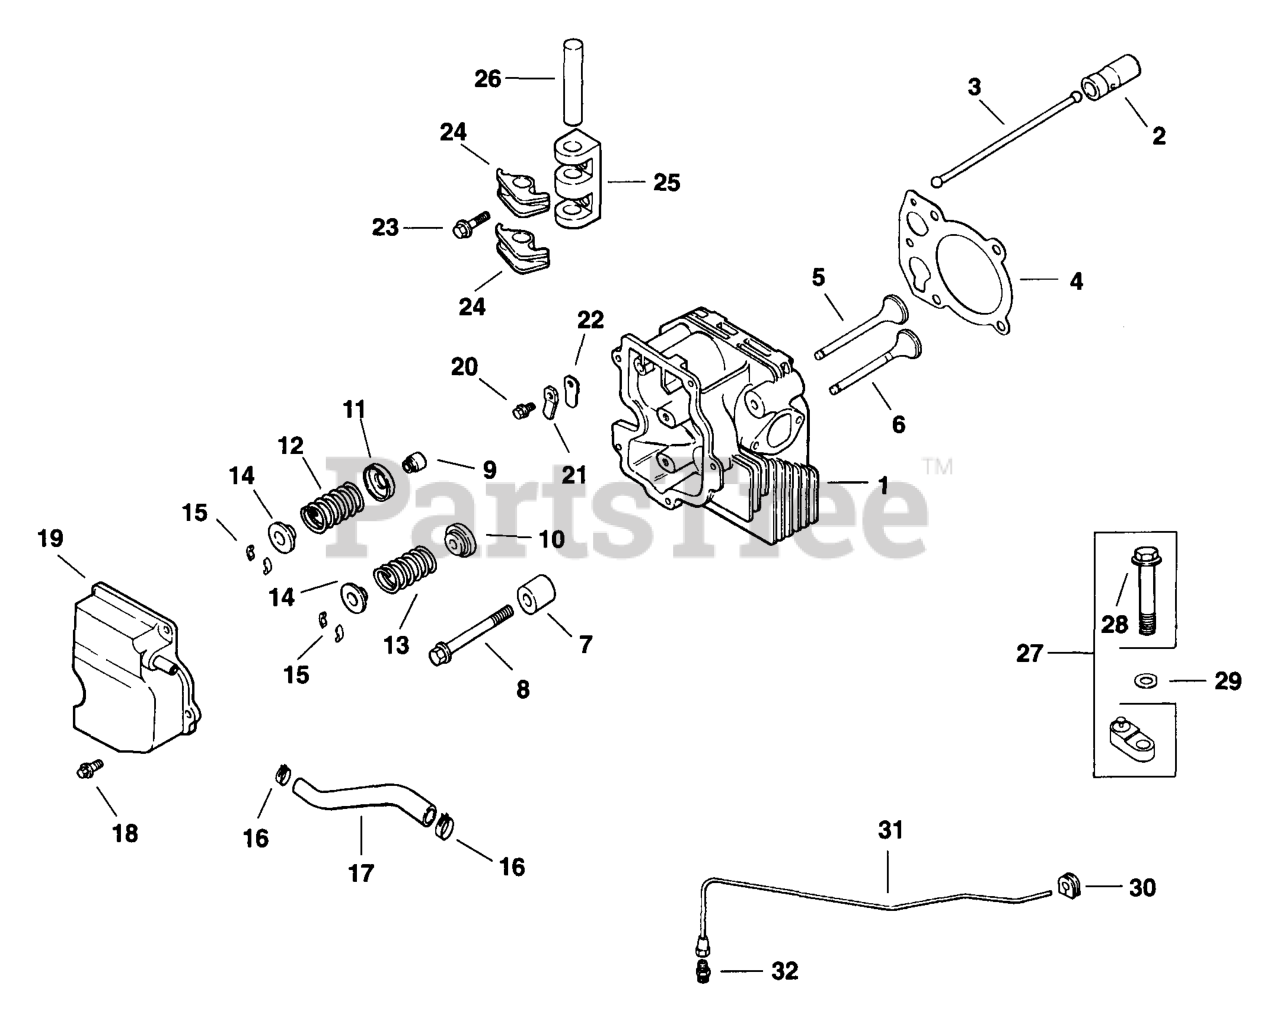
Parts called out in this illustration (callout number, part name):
1	Head, Cylinder
2	Lifter, Valve
3	Rod, Push
4	Gasket, Cylinder Head
5	Valve, Intake (Std.)
5	Valve, Intake (.25 O.S.)
6	Valve, Exhaust (Std.)
6	Valve, Exhaust (.25 O.S.)
7	Spacer, Head Bolt Exhaust Port (20 Mm Height)
8	Screw, Hex. Flange M10x1.5x80
9	Seal, Valve Stem
11	Spring, Retainer
12	Spring, Intake Valve
13	Spring, Exhaust Valve
14	Cap, Valve Spring
15	Kit, Retainer
16	Clamp, Hose
17	Hose, Breather
18	Screw, Hex. Flange M6x1.0x20
19	Cover, Valve W/Nipple
20	Screw, Hex. Flange M5x0.8x10
21	Retainer, Breather Reed
22	Reed, Breather
23	Screw, Hex. Flange M6x1.0x25
24	Arm, Rocker
25	Bridge, Rocker Arm
26	Shaft, Rocker Arm
